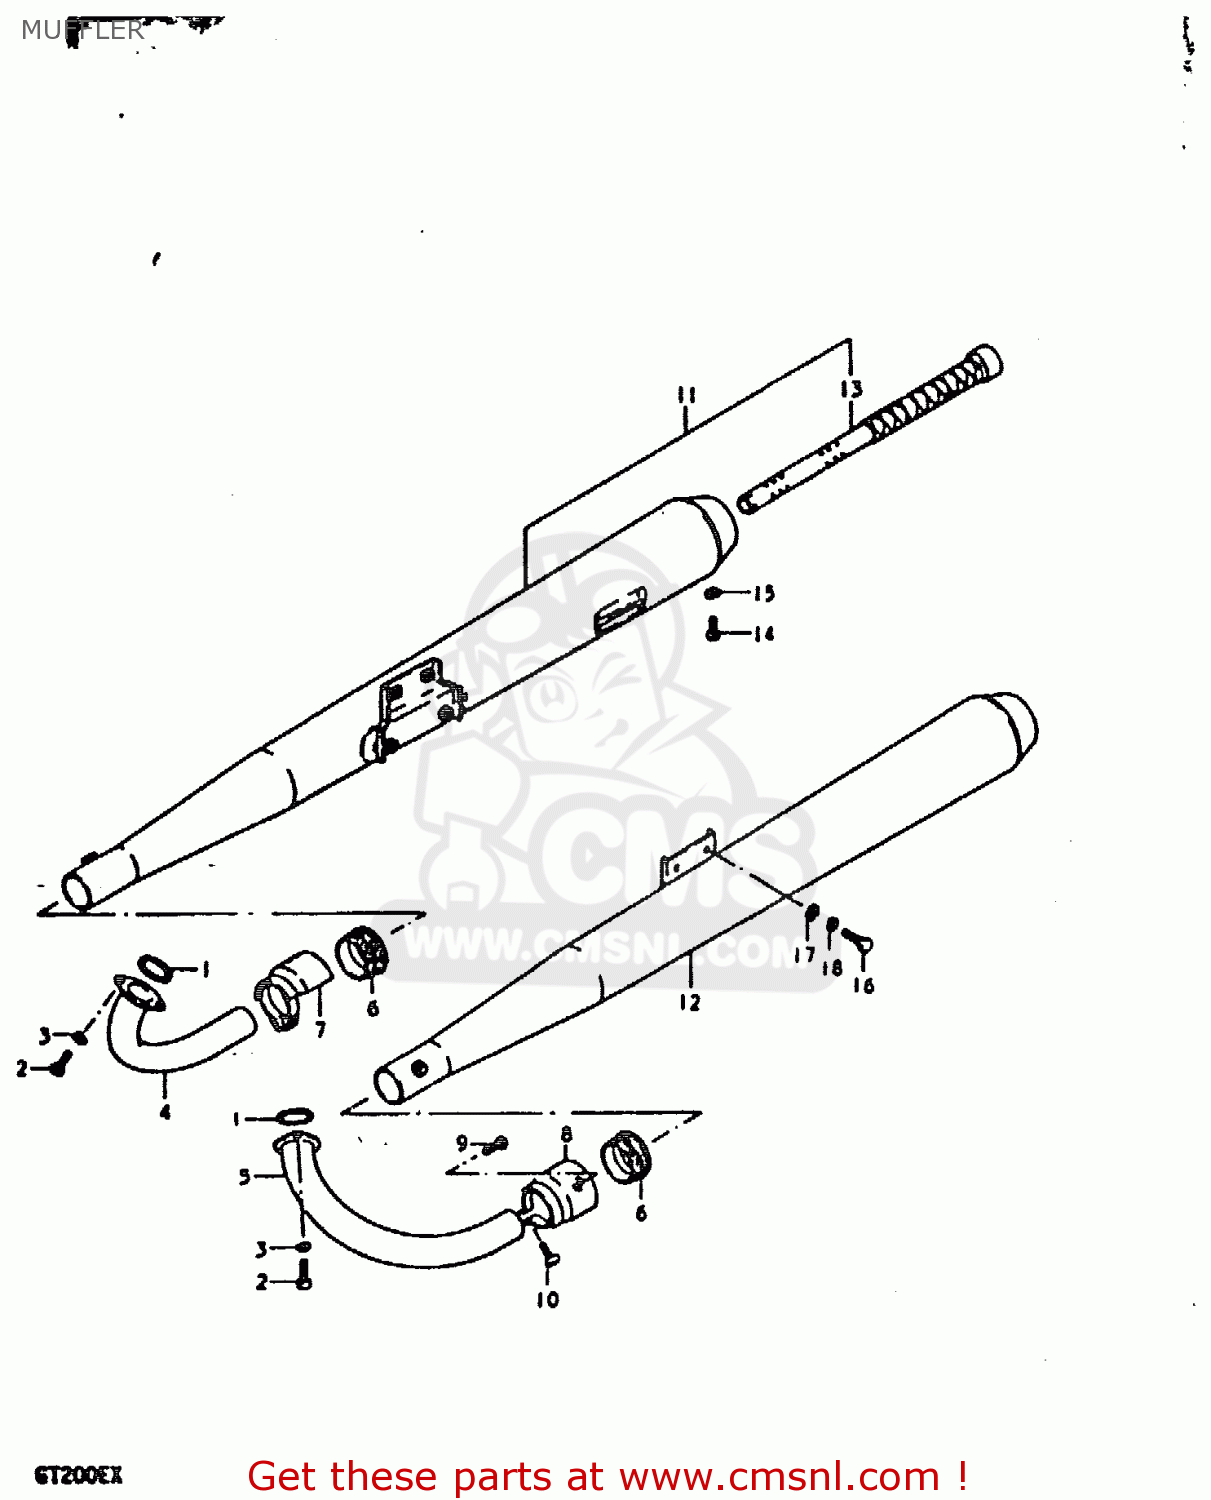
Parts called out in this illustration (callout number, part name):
1	GASKET,EXHAUST PIPE (NAS)
2	BOLT
3	LOCK WASHER
4	PIPE, EXHAUST RH
5	PIPE, EXHAUST LH
6	CONNECTOR,MUFFLER
7	COVER, RH
8	COVER, LH
9	SCREW
10	SCREW
11	MUFFLER ASSY, RH
12	MUFFLER ASSY, LH
13	PIPE,BAFFLE
14	BOLT(5X8)
15	LOCK WASHER
16	BOLT
17	WASHER
18	LOCK WASHER
